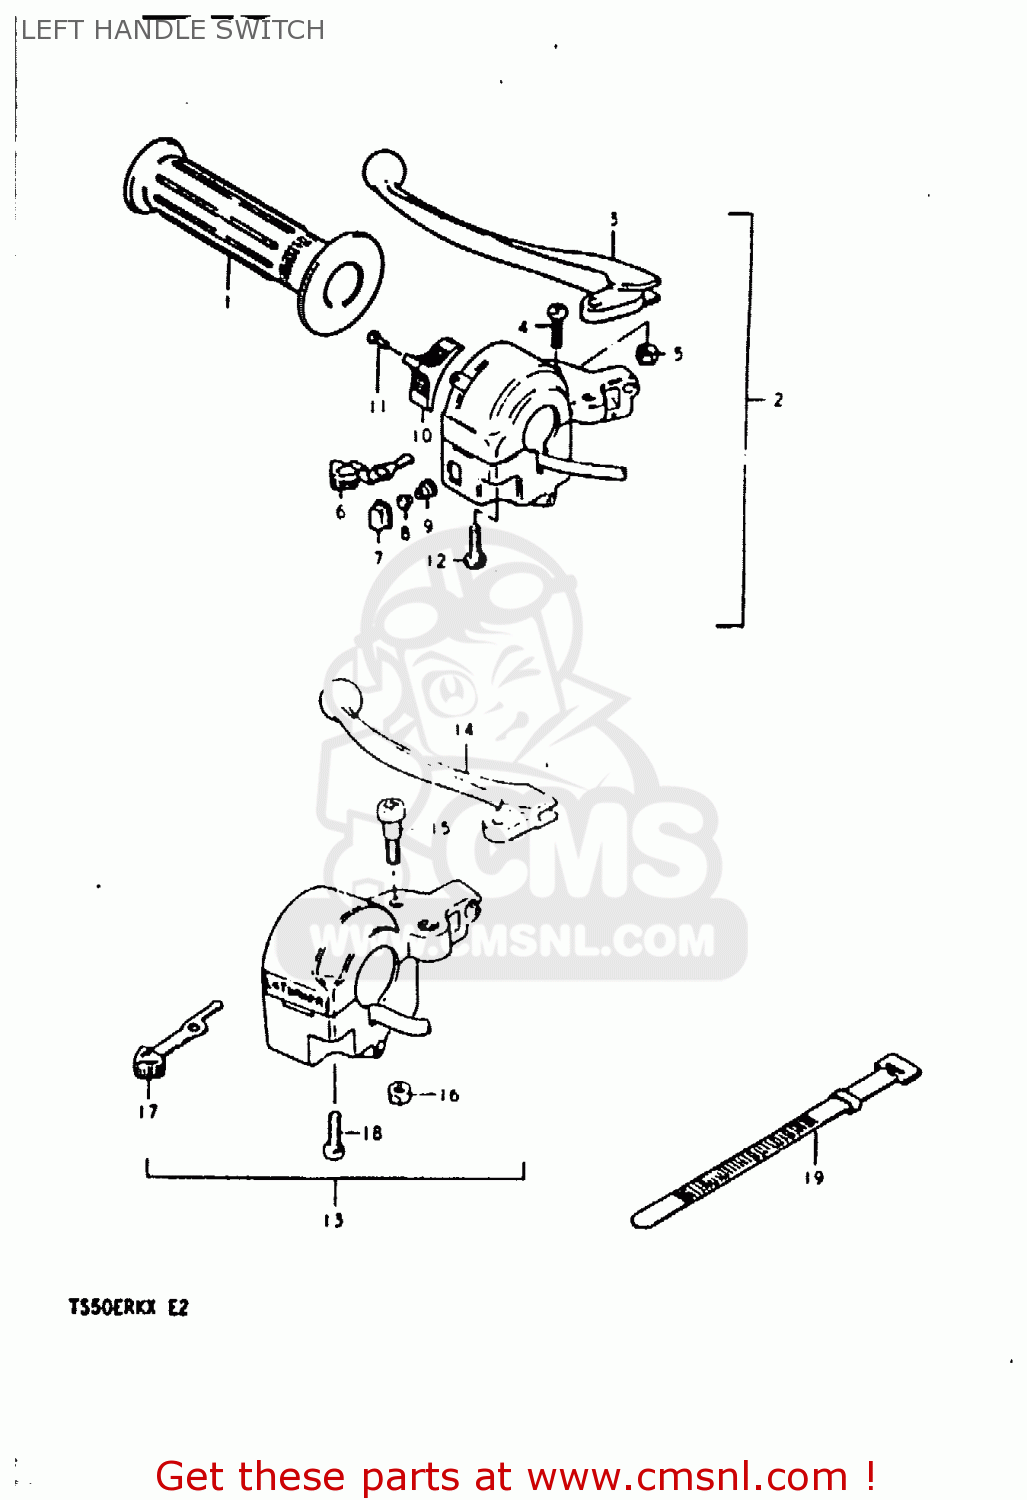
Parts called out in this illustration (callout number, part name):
1	GRIP,L
2	LEVER ASSEMBLY
3	LEVER
4	BOLT,LEVER
5	NUT,LEVER BOLT
6	KNOB,TURN SIGNAL SWITCH
7	BUTTON,HORN
8	CONTACT
9	SPRING
10	KNOB
11	SCREW 3X6
12	SCREW
19	CLAMP(L:120)
